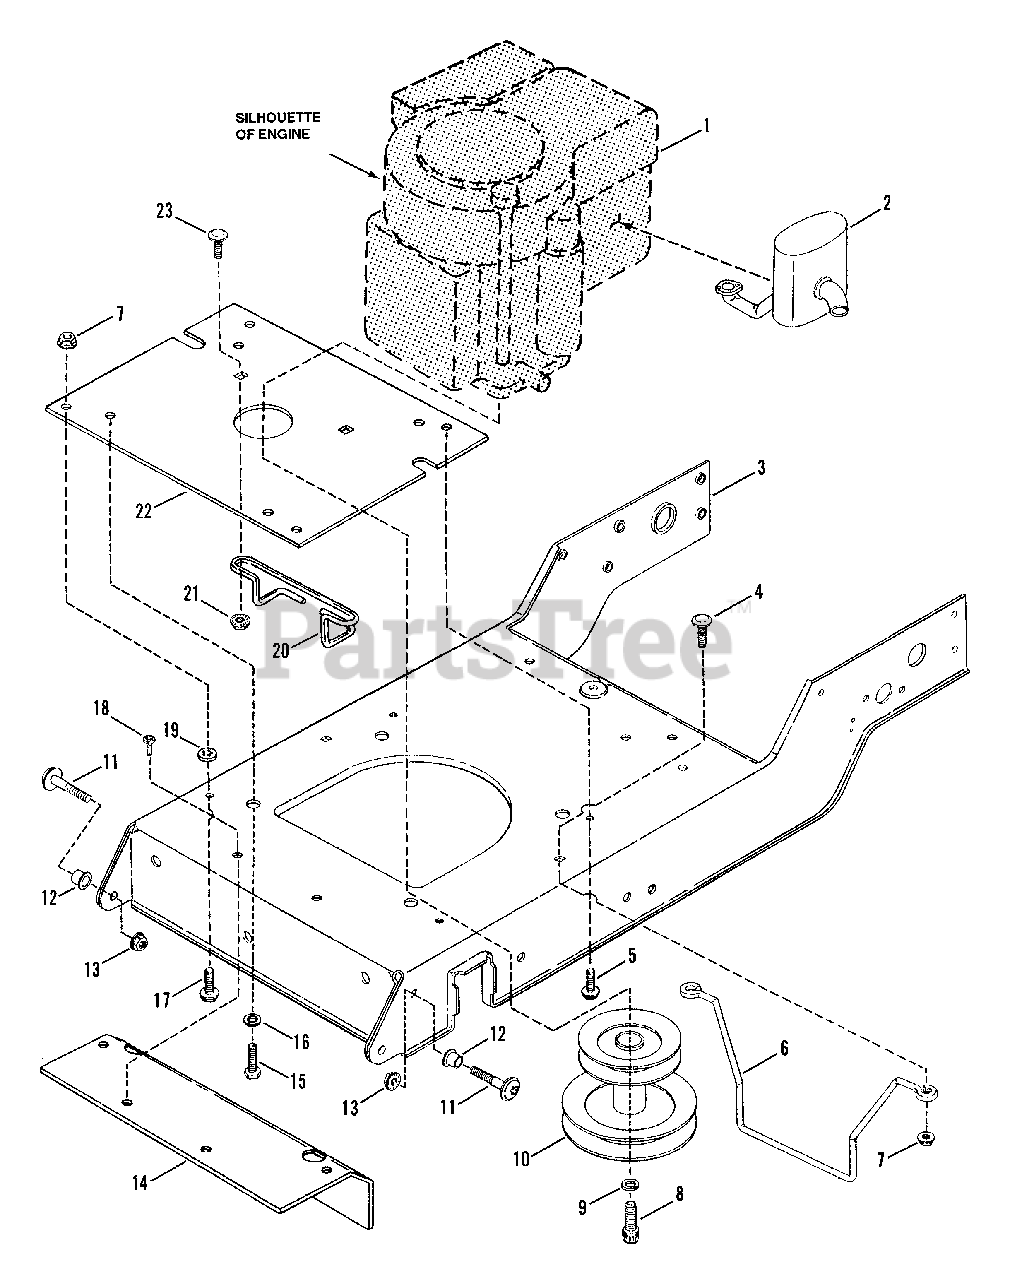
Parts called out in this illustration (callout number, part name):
2	MUFFLER, Exhaust
3	BASE, Engine
4	BOLT, 5/16-18 x 3/4" Short Neck Carriage
5	BOLT, 5/16-18 x 3/4" Hex Flange Lock
6	GUIDE, Belt
7	NUT, 5/16-18 Hex Flange Lock
8	SCREW, 7/16-20 Socket, Hex Head Cap
9	WASHER, 7/16 Split Lock
10	DRIVE PULLEY ASSEMBLY, Engine
11	SCREW, Shoulder, 3/8-16 x 1 5/8"
12	BUSHING
13	NUT, 3/8-16 Hex Flange Lock
14	AXLE SUPPORT
15	BOLT, M8-1.25 x 25MM Hex Head
16	WASHER, 5/16 Split Lock
17	BOLT, 5/16-18 x 1" Hex Flange Lock
18	SCREW, 5/16-18 x 5/8" Truss Head Torx
19	RETAINER
20	GUIDE, Belt
21	NUT, 1/4-20 Hex Flange Lock
22	SPACER, Kohler Engine
23	BOLT, 1/4-20 x 5/8" Short Neck Carriage
